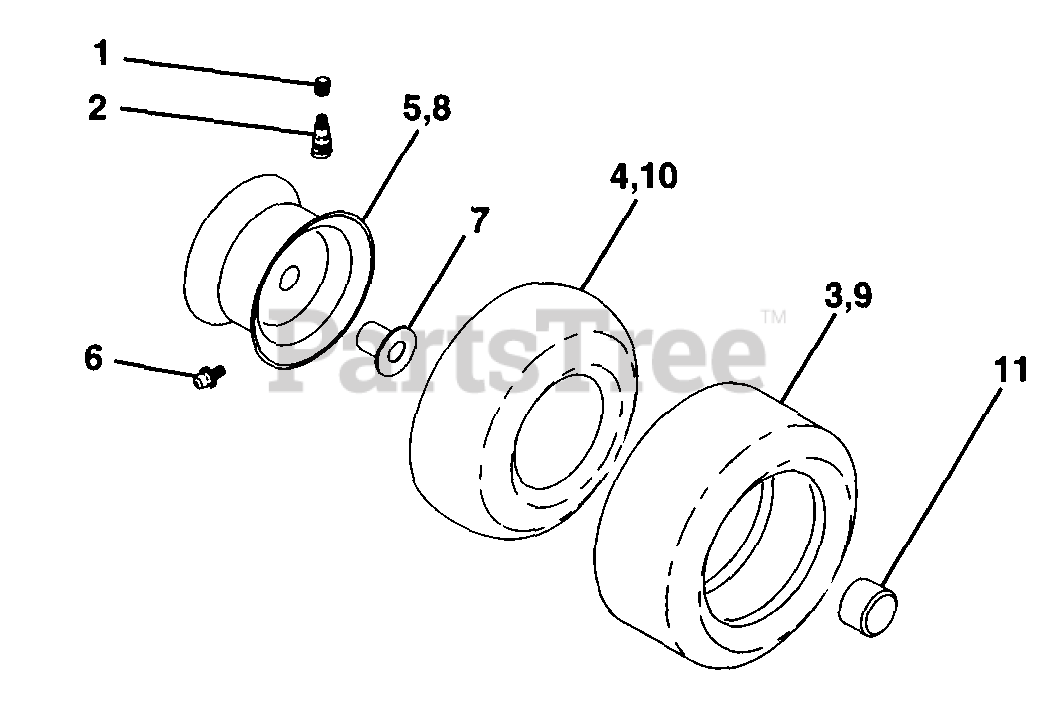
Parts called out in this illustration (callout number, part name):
1	Cap Valve Tire
2	Stem Valve
3	Tire F Ts 15 X 6 0 - 6 Service
4	Tube Front (Service Item Only)
5	Rim Asm 6"front Silver Service
6	Fitting Grease (Front Wheel Only)
7	Bearing Flange (Front Wheel Only)
8	Rim Asm 8" rear Silver Service
9	Tire R Ts 18 x 8 5-8 C Service
10	Tube Rear (Service Item Only)
11	Cap Axle Blk 1 50 X 1 00
